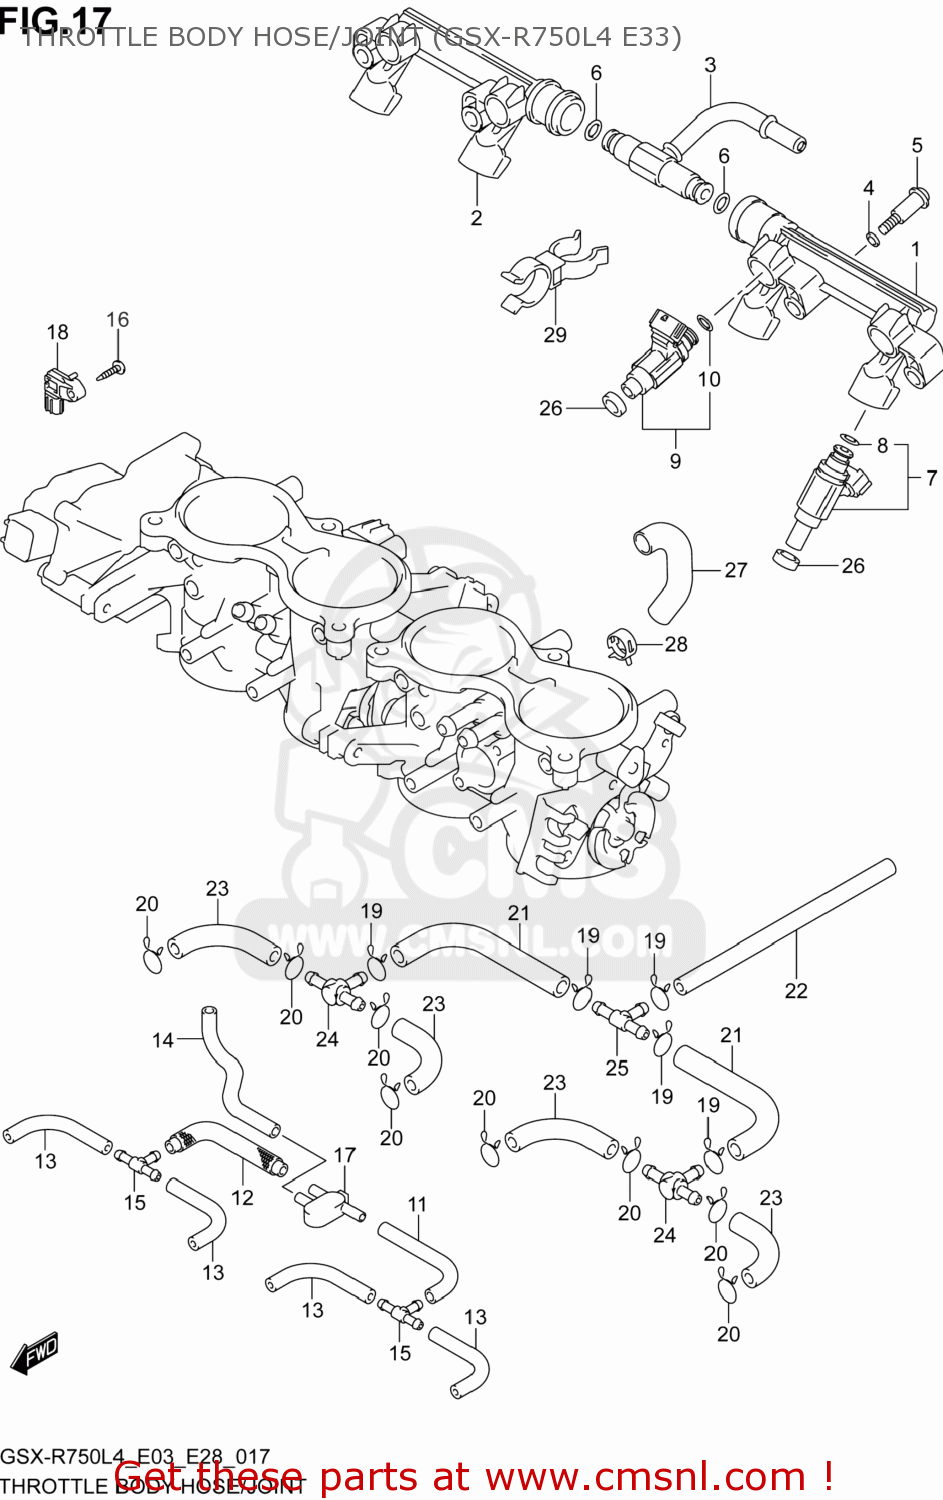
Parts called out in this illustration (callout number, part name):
1	DELIVERY PIPE
2	DELIVERY PIPE
3	NIPPLE ASSY
4	PACKING (NAS)
5	SCREW
6	O RING
7	INJECTOR ASSY
8	O-RING
9	INJECTOR ASSY
10	O-RING
11	HOSE
12	HOSE
13	HOSE(L:425)
14	HOSE
15	3WAY,VACUUM HOSE
16	SCREW
17	JOINT
18	SENSOR,BOOST
19	CLIP
20	CLIP
21	HOSE
22	HOSE
23	HOSE
24	NIPPLE
25	NIPPLE
26	SEAL
27	HOSE
28	CLIP
29	CLAMP
